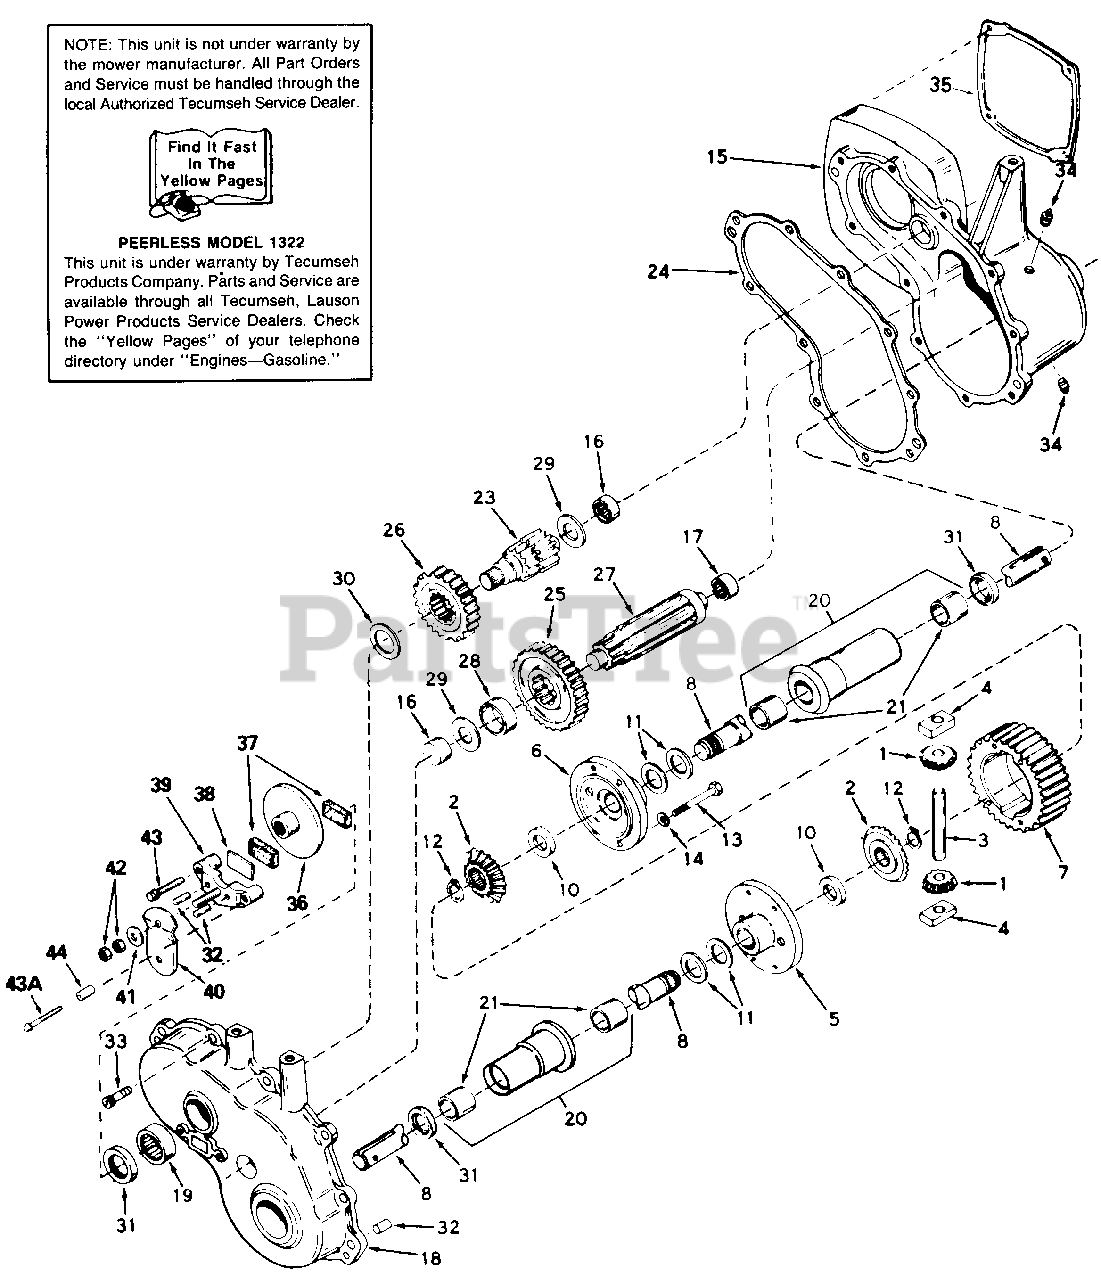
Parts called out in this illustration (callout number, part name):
1	Pinion: Bevel
2	Gear: Bevel
3	Pin: Drive
4	Block: Drive
5	Carrier: Differential
6	Carrier: Differential
7	Gear: Ring
8	Axle (16-1/64" Long)
10	Washer
11	Washer: Thrust
12	Ring: Snap
13	Screw: Hex Hd. 1/4-20 x 21/4
14	Lock Washer: 1/4"
15	Case Ass'y.
16	Bearing: Needle
17	Bearing: Needle
18	Cover Ass'y.
19	Bearing: Needle
20	Housing Ass'y.: Axle
21	Bushing
23	Shaft: Brake
24	Gasket: Case to Cover
25	Gear: Output
26	Gear: Idler
27	Shaft: Output
28	Spacer
29	Washer
30	Washer
31	Seal: Oil
32	Pin: Dowel
33	Screw: Hex Hd.: Self-Tapping: 1/4-20 x 1
34	Plug: Pipe
35	Gasket
36	Disc: Brake
37	Pad: Brake
38	Plate: Brake Pad
39	Holder: Brake Pad
40	Lever: Brake
41	Washer: Flat
42	Lock Nut 5/16-24
43	Screw: Hex Hd.: Self-Tapping: 1/4-20 x 1-1/4
43A	Screw: Hex Hd.: Self-Tapping: 1/4-20 x 2-1/4
44	Spacer
